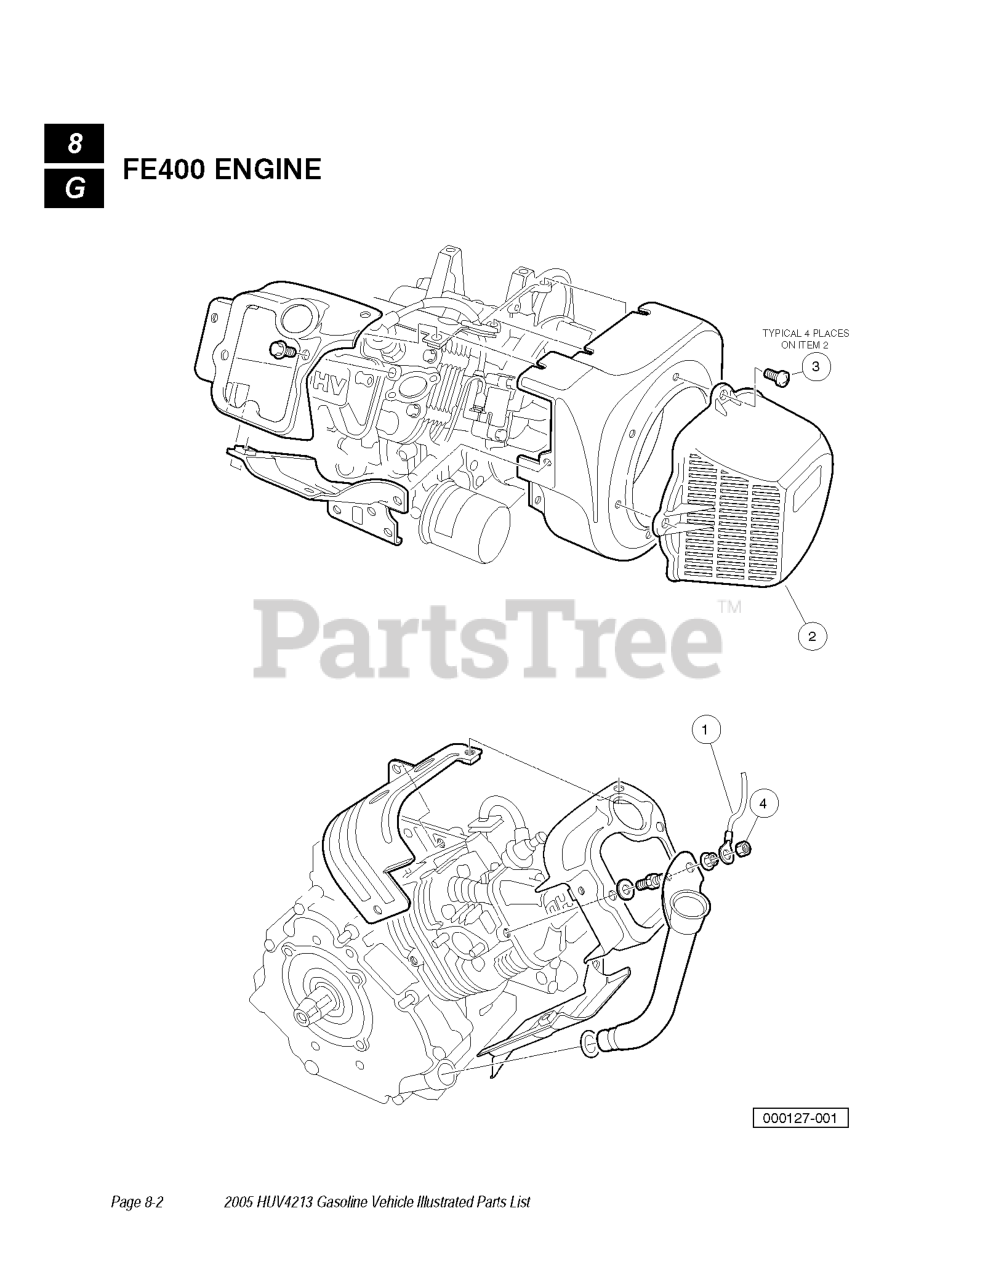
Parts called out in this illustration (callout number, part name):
1	WIRE ASM
2	SHROUD, FAN
3	SCREW, M6-1.00 X 10MM PAN HD
4	LOCKNUT, M6-1.00 NYLON INSERT
5	FE 400 ENGINE (CW)
